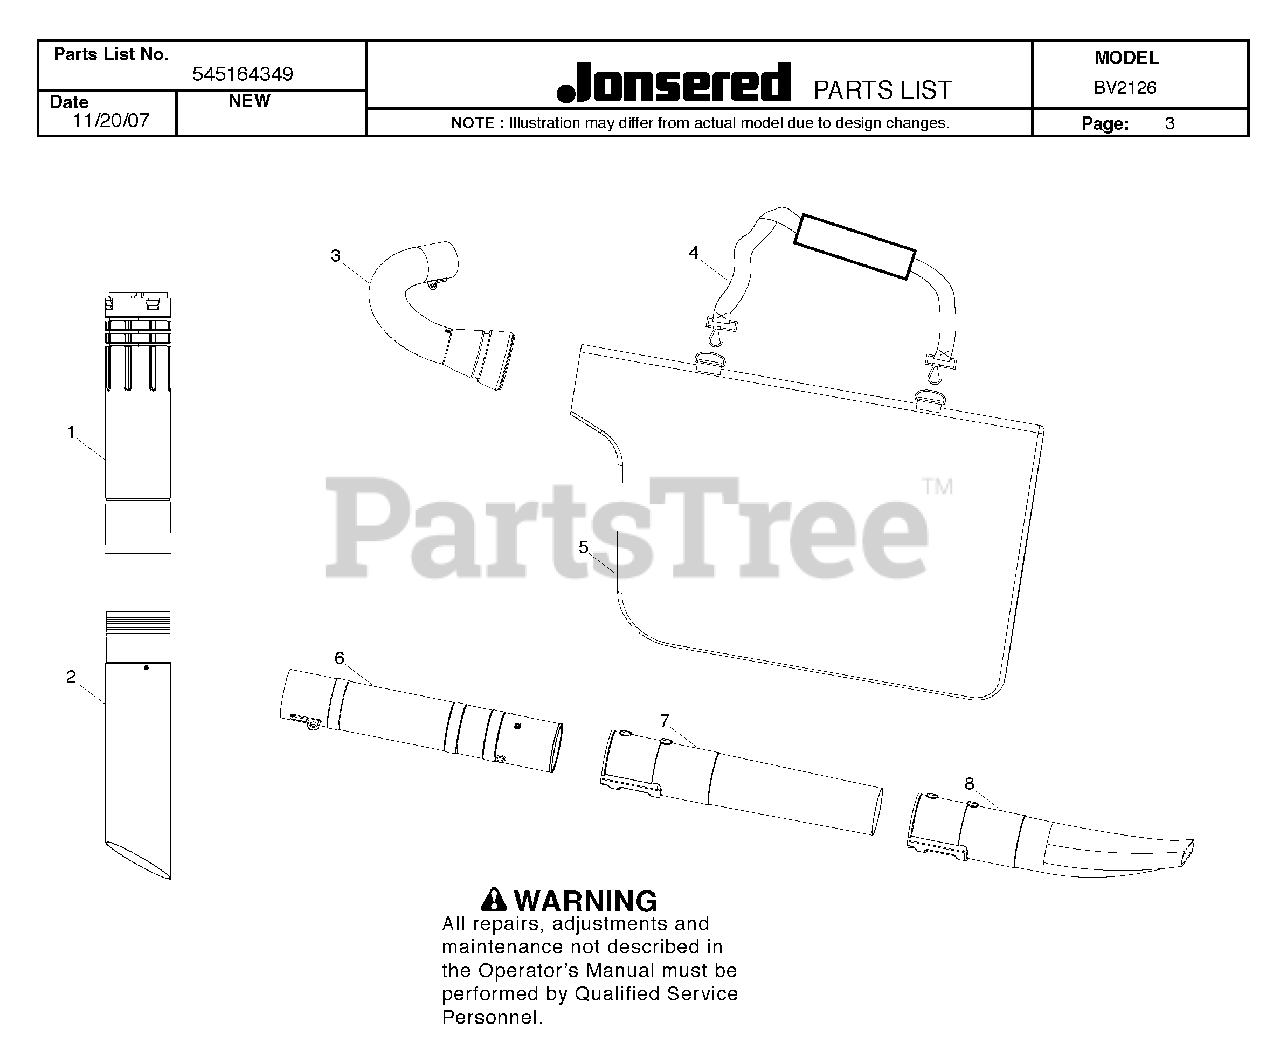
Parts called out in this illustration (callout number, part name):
1	ASSY - UPPER VAC TUBE
2	TUBE - LOWER VAC
3	TUBE - ELBOW
4	%STRAP
5	VACUUM BAG
7	TUBE - LOWER BLOWER
8	TUBE-LOWER BLOWER FLARE
